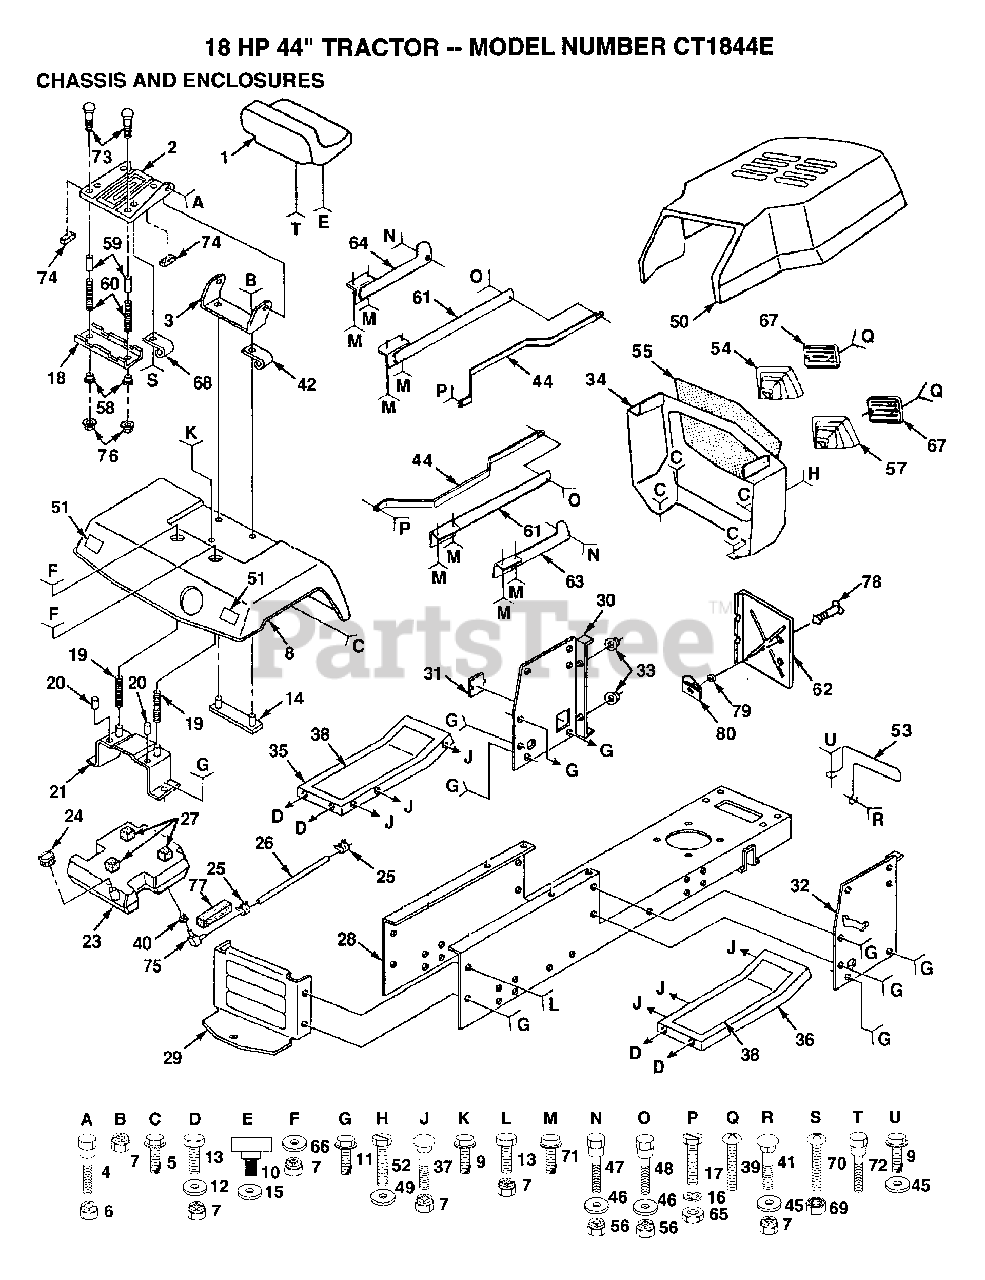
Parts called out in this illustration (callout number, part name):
5	SCREW LT
9	SCREW GTV
10	"KNOB 1/2"" YT"
11	SCREW
12	WASHER
15	WASHER
16	LOCKWASHER
18	BRKT SWITCH
19	SPRING COMPRESSIO
20	NUT-PUSH YT
25	HOSE CLAMP
27	PAD-SPACER LT
28	CHASSIS
29	DRAWBAR LT/YT
30	PANEL.DASH.LH
31	COVER ACCESS
32	PANEL.DASH.RH
37	BOLT
38	FOOTREST PAD
40	BUSHING OUTLET T
41	BOLT D
42	CLIP T
45	WASHER HYT
47	BOLT T
48	"BOLT,SHOULDER"
51	REFLECTOR-TAIL YT
52	SCREW
53	MUFFLER GUARD
55	SCREEN GRILL GTV
58	BUSHING
59	SPACER SPLIT
60	SPRING COMPRESSED
61	STRAP ASSY-REAR T
62	HEAT SHIELD
63	STRAP ASSY T
64	STRAP ASSY T
66	WASHER
69	"NUT,KEPS"
72	"BOLT,SHOULDER"
74	STRIP FORM
75	FUEL TANK STEM GT
77	PAD IDLER TI
78	STUD.1/4.TURN
79	RETAINER LT
80	RECEPTACLE LT
